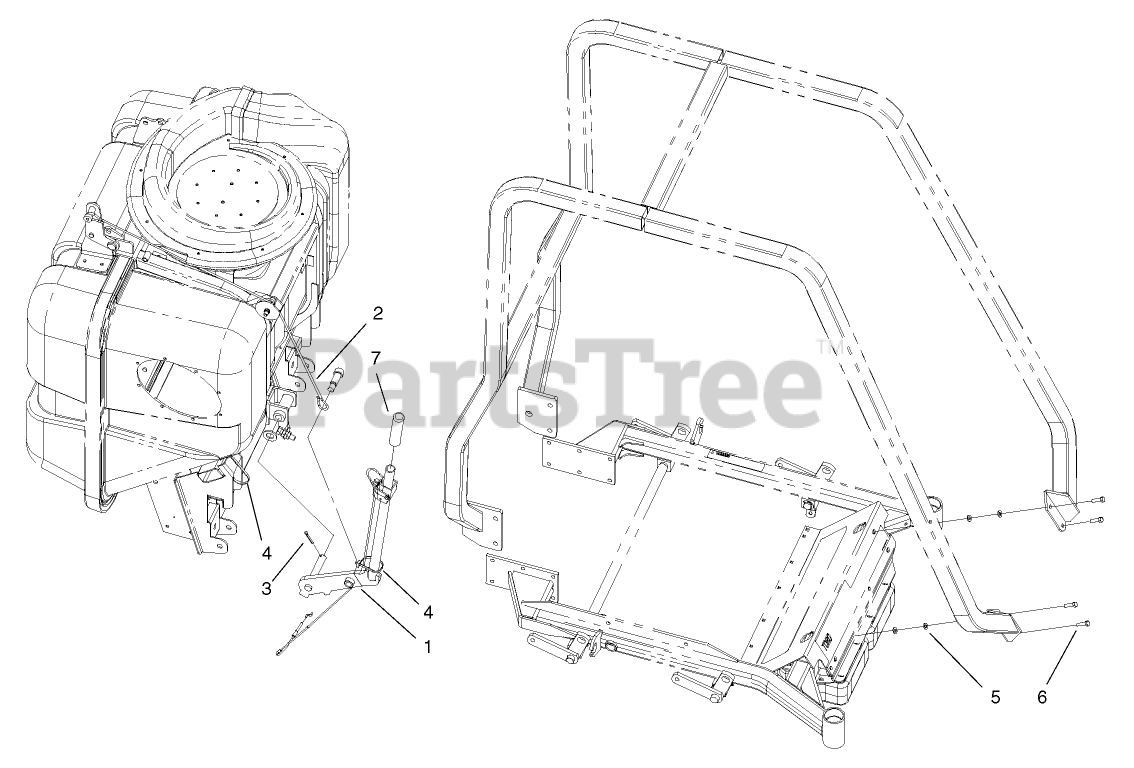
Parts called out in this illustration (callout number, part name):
1	Dump Arm ASM
2	Cable-Door
3	PIN-COTTER
4	TIE-CABLE
5	WASHER-PLAIN
6	SCREW-HH
7	GRIP-FOAM
